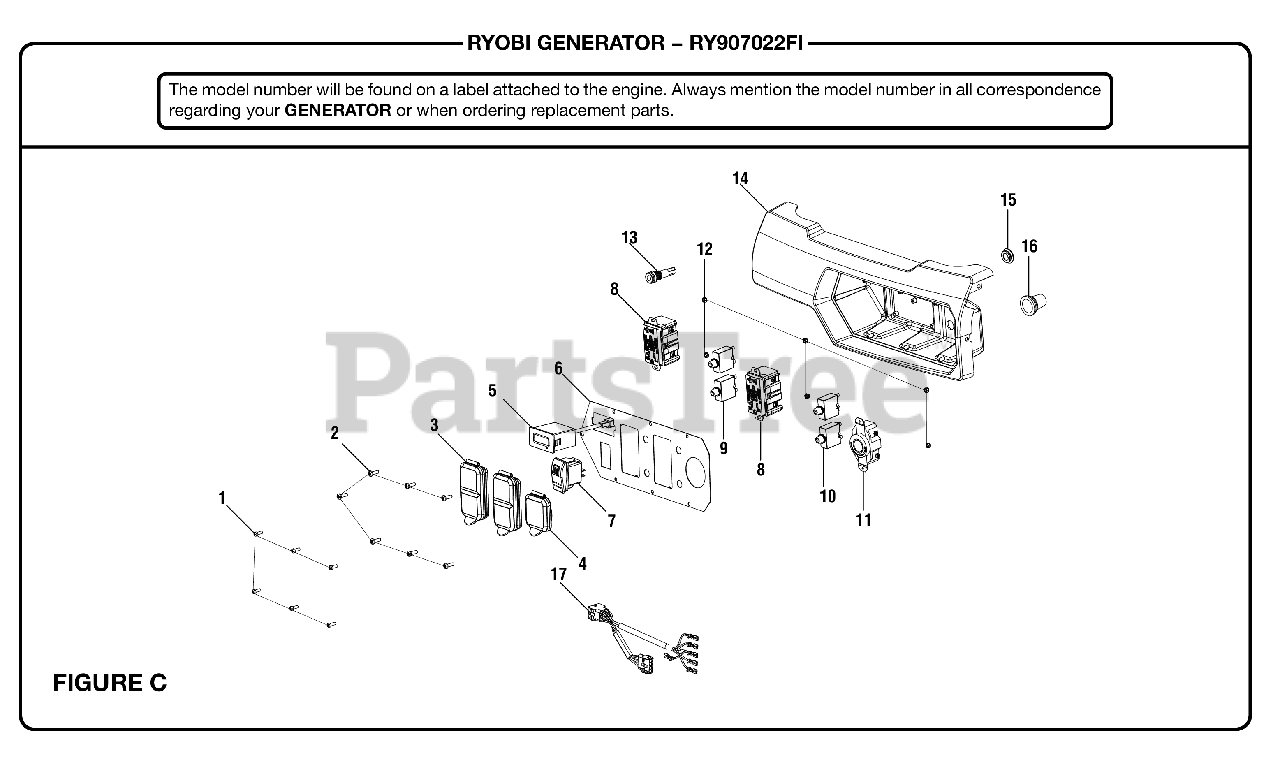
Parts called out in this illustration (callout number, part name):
1	Screw (6-20 x 3/8 in., Phillips Pan Hd.)
2	Screw (#8-18 x 1/2 in., T20 Torx Pan Hd.)
3	120 Volt Receptacle Rain Cover
4	240 Volt ReceptacleRain Cover
5	Digital Display
6	Faceplate
7	Start/Stop Switch
8	Duplex Receptacle (120 Volt)
9	Circuit Breaker (20 Amp, 125 Volt)
10	Circuit Breaker 30 Amp 1 Pole
11	Twist Lock Recepticle (120/240 Volt, 30 Amp, L14-30)
12	Lock Nut (6-32, Hex Hd.)
13	12V LED w/Resistor Indicator
14	Control Box
16	Wiring Rubber Boot
17	Wiring Harness
